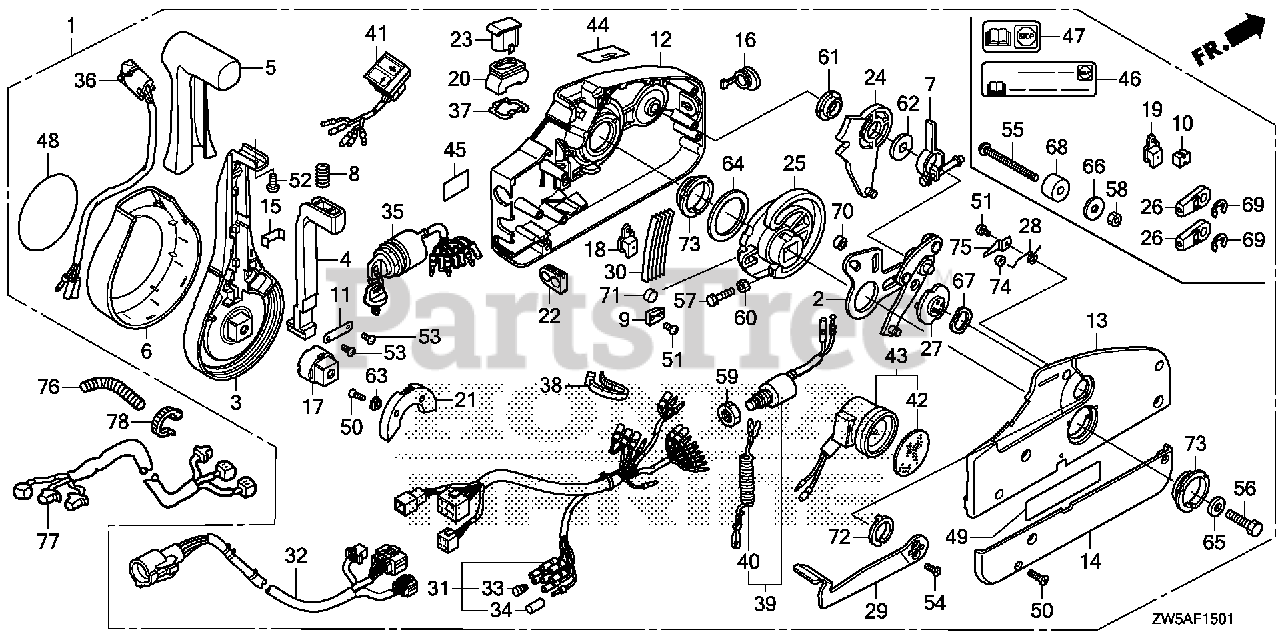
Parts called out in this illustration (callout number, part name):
1	BOX ASSY., REMOTE CONTROL (NHK MEC)
2	PLATE ASSY.
3	LEVER, HAND
4	ARM, NEUTRAL LOCK
5	GRIP
6	COVER, LEVER
7	ARM ASSY., BRAKE
8	SPRING (2)
9	CLIP, DETENT
10	SPACER (1) (LOOSE PARTS)
11	BRACKET
12	HOUSING, FR.
13	HOUSING, RR.
14	PANEL, BACK
15	BRACKET, WIRE CLAMP
16	CAP, RUBBER
17	ADJUSTER
18	COVER, POWER TRIM-TILT WIRE
19	COVER, POWER TRIM-TILT WIRE (LOOSE PARTS)
20	SEAL, RUBBER
21	HOLDER, NEUTRAL LOCK
22	GROMMET, WIRE (14)
23	CAP, TROLLING CONTROL SWITCH BLANK
24	GEAR ASSY., SHIFT
25	GEAR, DRIVE
26	TERMINAL, CABLE (LOOSE PARTS)
27	DRUM ASSY., FREE THROTTLE
28	SPRING (1)
29	LEVER, FREE THROTTLE
30	SPRING, DETENT
31	CABLE ASSY., REMOTE CONTROL (B)
32	CABLE ASSY., SWITCH PANEL
33	PLUG, CONNECTOR (INNER)
34	PLUG, CONNECTOR (OUTER)
35	SWITCH ASSY., COMBINATION
36	SWITCH ASSY., POWER TRIM-TILT
37	PLATE, SWITCH
38	BAND, WIRE
39	SWITCH ASSY., EMERGENCY STOP
40	WIRE, EMERGENCY
41	LAMP ASSY., INDICATION (2-LED)
42	PLATE, TURN SIGNAL BUZZER
43	BUZZER, WARNING
44	MARK, FAST IDLE
45	MARK, EMERGENCY STOP (US)
46	MARK, EMERGENCY STOP (US) (LOOSE PARTS)
48	MARK, EMBLEM
49	LABEL, SIGP
50	SCREW (5X18)
51	SCREW (4X6)
52	SCREW (5X10)
53	SCREW (4X10)
54	SCREW (5X12)
55	SCREW (6X90) (LOOSE PARTS)
56	BOLT (8X50)
57	BOLT (5X25)
58	NUT (6MM) (LOOSE PARTS)
59	NUT, HEX. (16MM)
60	NUT (5MM)
61	BEARING (1)
62	WASHER (3)
63	WASHER (4)
64	WASHER (5)
65	WASHER (8MM)
66	WASHER (7) (LOOSE PARTS)
67	WASHER, WAVE
68	SPACER (2) (LOOSE PARTS)
69	E-RING (6MM) (LOOSE PARTS)
70	ROLLER, DRIVE GEAR CAM
71	ROLLER
72	BEARING (2)
73	BEARING (3)
74	ROLLER, FREE THROTTLE
75	CLIP, ROLLER
76	TUBE, CORRUGATE (28MM)
77	CABLE ASSY., REMOTE CONTROL EXTENSION
78	BAND, SELF-LOCK
